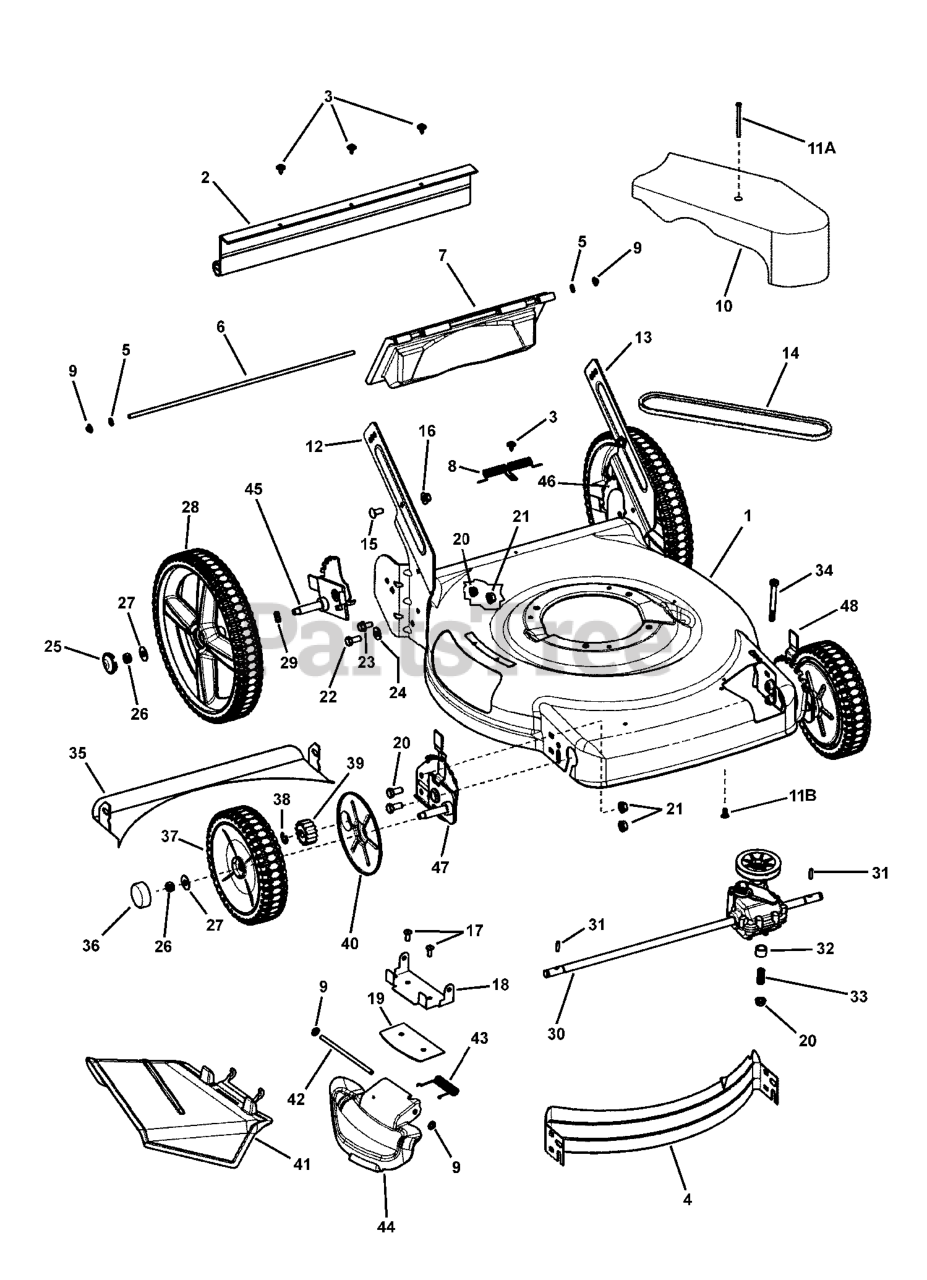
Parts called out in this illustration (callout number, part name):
1	DECK, 22 WALK, 3-N-1
2	GUARD, REAR 22 HW (19-1/2 long)
3	HWST, 10-24X.50 SEMS
4	BAFFLE, FRONT, 22 WBM
5	CAP, RETAINER
6	ROD, PIVOT, REAR DOOR
7	DOOR, REAR DISCHARGE, 22 WALK MOWER
8	SPRING, TORSION, REAR DOOR, 22 WBM
9	PUSHNUT, 1/4
10	COVER, BELT 22" (shown)
11A	SCREW, #10-24 X 2-1/2
11B	SCREW, Round Washer Head Torx, Hi-Lo
14	BELT, DRIVE 22 (3L Section;33.75 effective length)
15	RHSSNB, 5/16-18 X 3/4 GR5 YZ
16	LHCLN, 5/16-18 BLACK
17	TORX ST, 1/4-20 X 11/16
18	BRACKET, CHUTE
19	PLATE-MULCH, 22 RB SCOTT'S
20	NUT, HEX FLANGE LOCK, 5/16-18 NC
21	HFLN, 3/8-16, BRIGHT ZINC
22	HHCS, 3/8-16 X 3/4
23	HFLB, 5/16-18 X 5/8
24	FLW, .375 X .875 X .083 YZ
25	HUBCAP, 12 WHEEL, BLACK
26	HCLN, 3/8-16 YZ
27	WASHER, FLAT, 1 OD X .387 ID
28	WHEEL, 12X 2 IDLE, W/DB TRD, BRUTE YELLOW
29	WASHER, .531 X .781 3-WAVE
30	TRANSMISSION, 22 WBM SS, FWD
31	PIN, DRIVE, 22 WBM, FWD
32	SPACER, ENGINE
33	SPRING, COMPRESSION
34	BOLT, Hex-Head 5/16-18 X 3.00 P&OIL
35	BAFFLE, REAR, 22 DECK
36	HUBCAP, ROUND, BLACK
37	WHEEL, 8X 2 DRIVE, W/DB TRD, BRUTE YELLOW
38	RETAINING RING
39	GEAR, PINION, 22 WBM, FWD
40	SHIELD, DUST, 22 WBM, FWD
41	CHUTE, SIDE, PLASTIC, BLACK
42	ROD, PIVOT, CHUTE
43	SPRING, TORSION, CHUTE
44	COVER, MULCH, PLASTIC, BLACK
45	ASSY, Height-Of-Cut, RR, 22", 7 Position (shown detached)
46	ASSY, Height-Of-Cut, LR, 22", 7 Position (shown attached)
47	ASSY, Height-Of-Cut, RF, 22", Propelled, 7 Position (shown detached)
48	ASSY, Height-Of-Cut, LF, 22", Propelled, 7 Position (shown attached)
